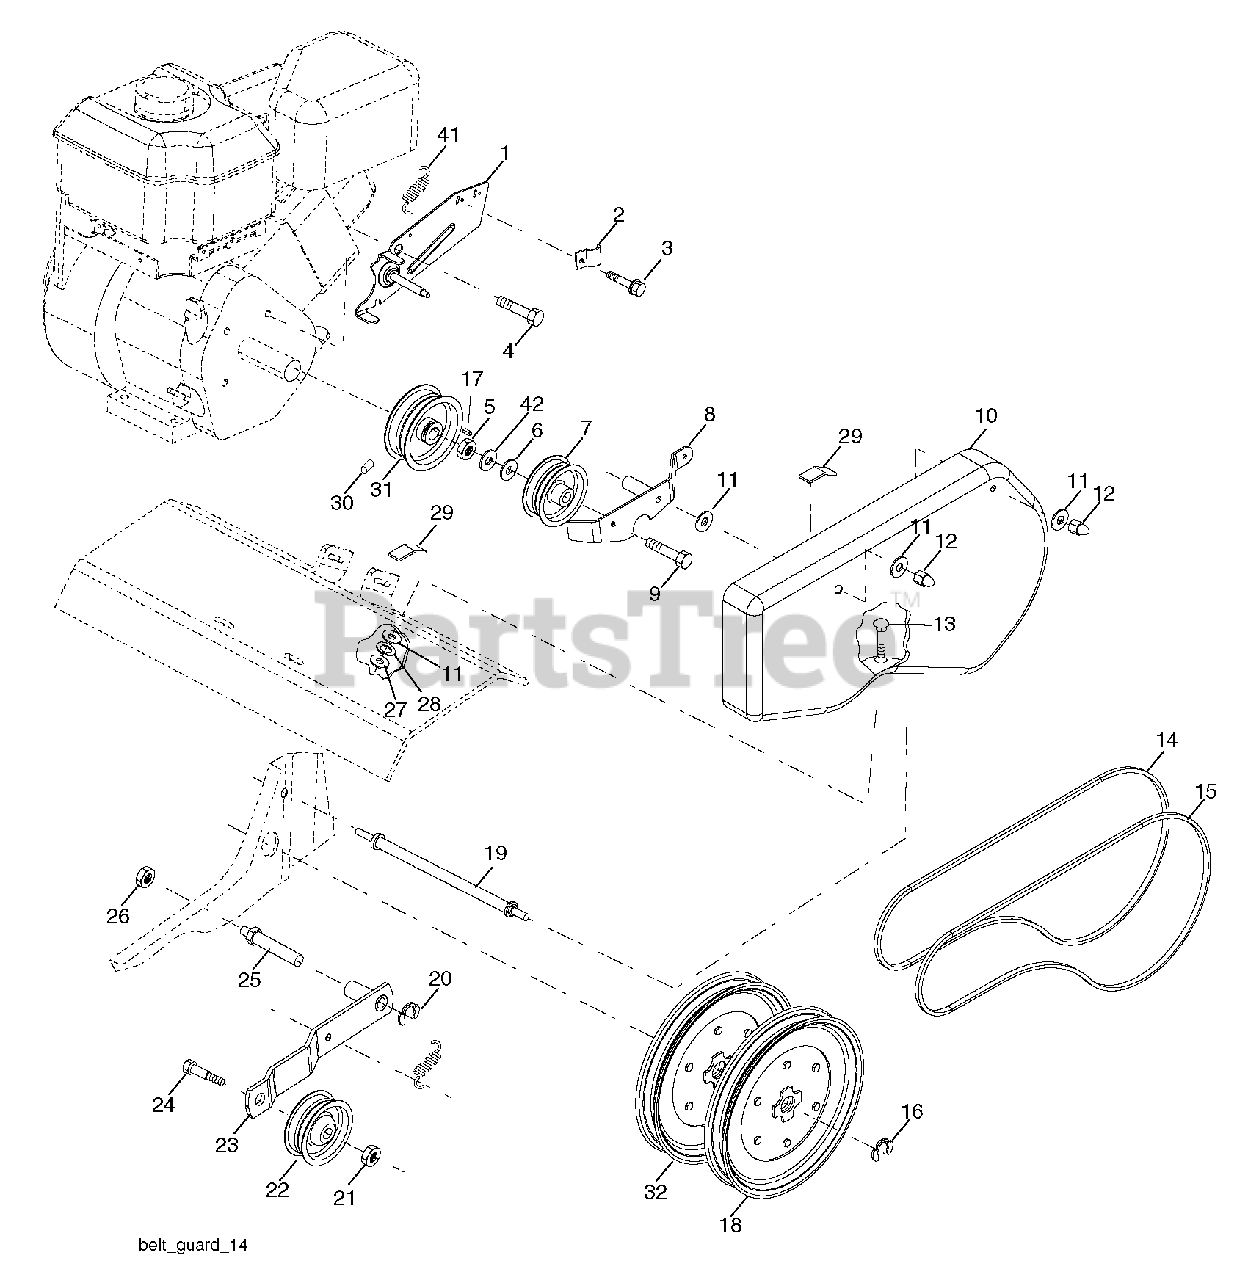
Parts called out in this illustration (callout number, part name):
1	Assembly, Bracket, Belt Guard
2	Clip, Cable
3	Screw #10-24 x 1/2
4	Bolt, Hex Head 1/2-20 x 3/4
5	Nut, Hex 3/8-16
6	Washer 13/32 x 13/16 x 16 Ga.
7	Pulley, Idler, Reverse
8	Assembly, Arm, Reverse Idler
9	Bolt, Hex Head 3/8-16 x 1-3/4
10	Guard, Belt
11	Washer 9/32 x 5/8 x 16 Ga.
12	Nut, Cap 1/4- 20
13	Bolt, Carriage 1/4-20 x 3/4
14	V-Belt (Forward Motion)
15	V-Belt (Reverse)
16	Ring, Retainer
17	Key, Square
18	Sheave, Transmission "Flat"
19	Bolt, Belt Guard
20	Ring, Klip
21	Nut, Hex, Jam 3/8-16
22	Pulley, Idler
23	Arm, Idler
24	Bolt 3/8-16 x 1-1/4
25	Shaft, Idler Arm
26	Nut, Hex, Jam 5/16-18
27	Nut, Hex 1/4-20
28	Washer, Lock 1/4
29	Pad, Idler
30	Screw, Set , Socket, Headless C.P. 1/4-20 x 1/4
31	Sheave, Engine
32	Sheave, Transmisison
41	Spring Extension
